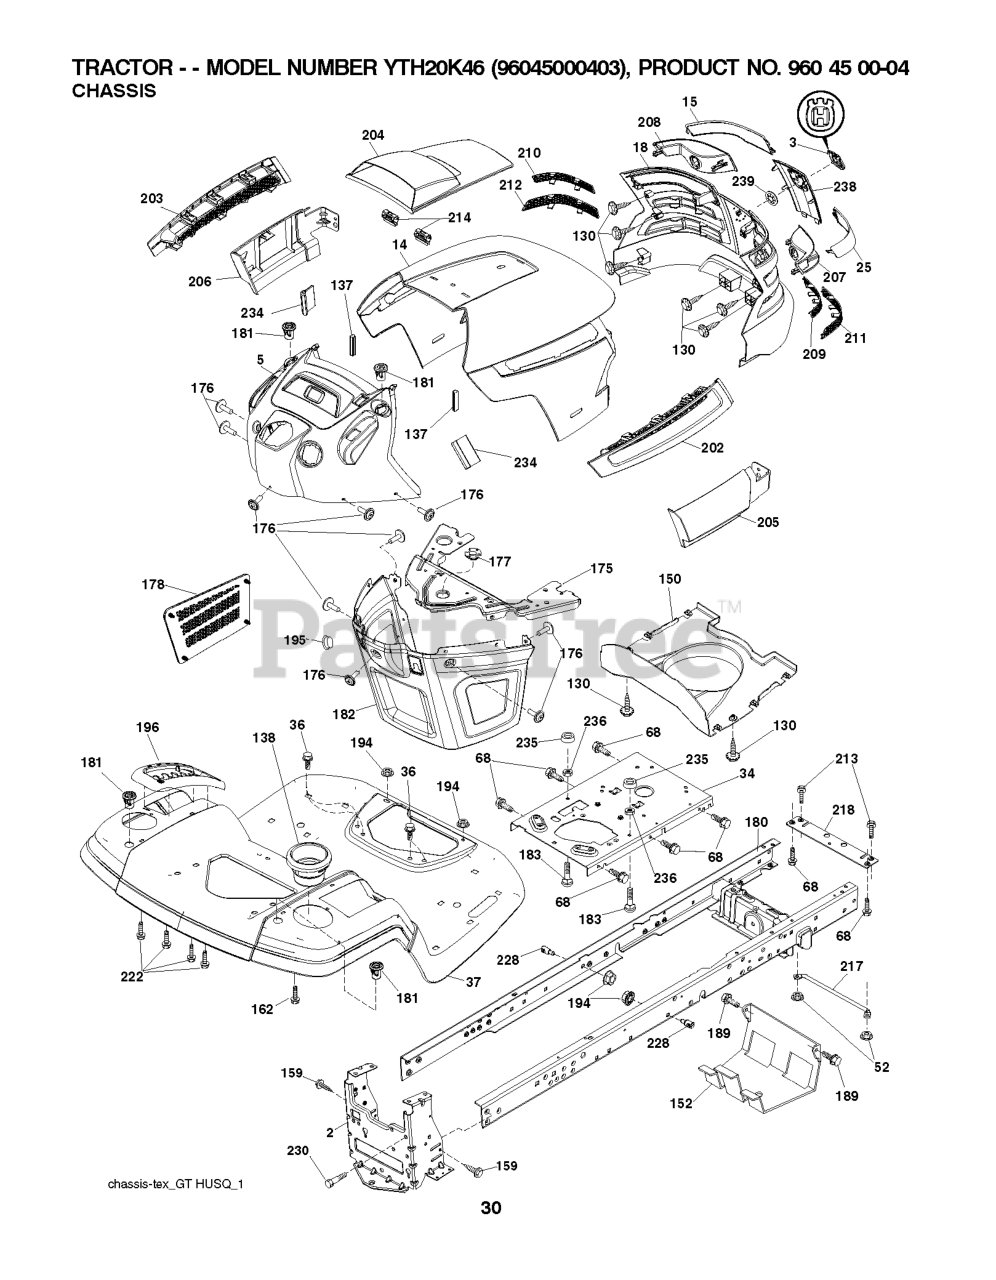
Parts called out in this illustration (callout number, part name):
2	DRAWBAR.1PC.NSTL
3	RP LOGO
4	LOGO
14	HOOD
15	LENS.LH.TEX.GT.HUSQ.CL
18	GRILL.ASM.HUSQ.TG/CRD.W/TRIM
25	LENS.RH.TEX.GT.HUSQ.CL
34	PLATE.ENGINE.WELDED.CHASSIS
36	SCREW 5/16"
37	FEND/FTRST.PCH.CPH.NFW
52	LOCKNUT
68	Screw 5/16-18 x 1/2 Hex, Self Tapping 5/16-18 x 1/2
130	SCREW
137	BUMPER DASH
138	CUPHOLDER.TL.TEX.418
150	AIR.DUCT.TEXGT.HUSQ.SV
152	SHIELD.BROWNING.W/TEX
159	SCREW, 3/8-16X3/4
162	SCREW.HI-LO.CONSOLE
175	PLATE.CROSSMEMBER.HUSQ
176	SCREW.#10-24X5/8.RN.QU
177	BUSHING, STEERING
178	CARGO.ASM.NET.TXGT.W/C
180	CHASSIS
181	BUSHING.MNT.FEND.CRGO.
182	DASH.LOWER.COMMON.12V.
183	BOLT.5/16-18X1-1/4 FULL.THREAD
189	SCREW
194	NUT LOCK HEX FLANGE 5/16-18
195	PLUG.HOLE.DASH.LOWER.12V.BLK
196	CONSOLE.ASM.DECK.LIFT.
202	VENT.SIDE.HOOD.HUSQ.RH.GREY
203	VENT.SIDE.HOOD.HUSQ.LH.GRAY
204	VENT.TOP.HOOD.HUSQVARN
205	SKIRT.HOOD.SIDE.HUSQ.RH.GREY
206	SKIRT.HOOD.SIDE.HUSQ.LH.GREY
207	BEZEL.RH.TEX.GT.HUSQ
208	BEZEL.LH.TEX.GT.HUSQ
209	INSERT.HEX.GRILL.HUSQ.GREY
210	INSERT.HEX.GRILL.HUSQ.
211	INSERT.HEX.GRILL.HUSQ.
212	INSERT.HEX.GRILL.HUSQ.
213	BOLT
214	CLIP.RETAINER.TINNER.
217	ROD.PIVOT.HOOD
218	X-PIECE.HOOD.STOP.NON/
222	SCREW.1/4-20X5/8
228	STUD.FASTNER.W/ANTI-ROTATE
230	SHOULDER BOLT 5/16-18TT
234	BUMPER.HOOD.TEX.HUSQVARNA
235	SPACER FENDER
236	NUT.CENTERLOCK.5/16-
238	TRIM.HUSQ.TG/CRD.SERVICE
239	NUT PUSH M
